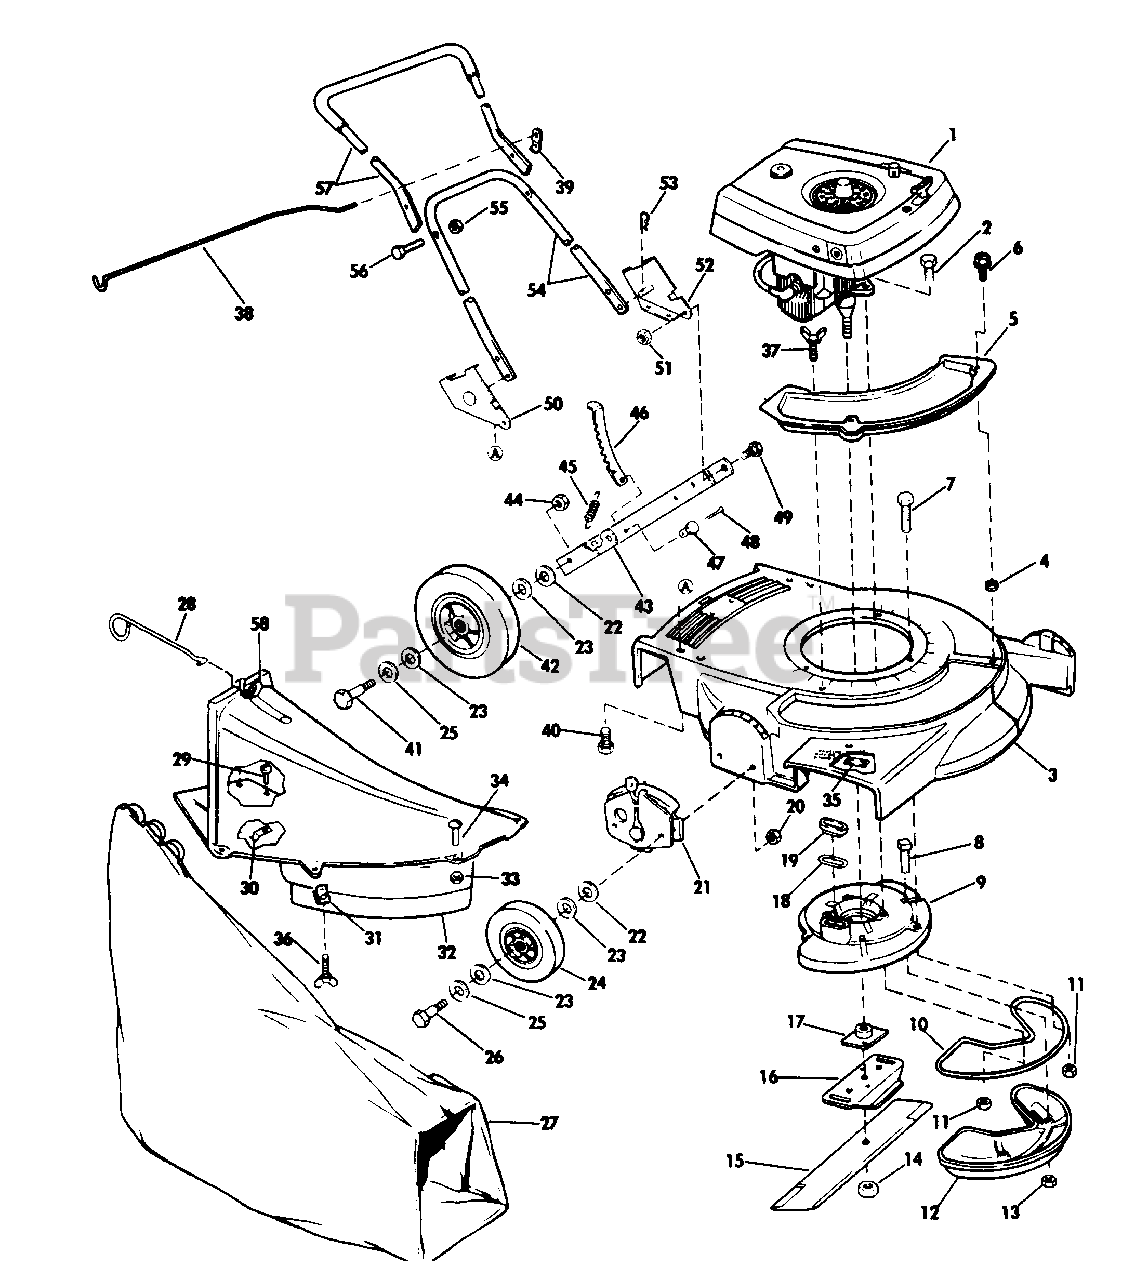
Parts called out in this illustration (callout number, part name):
1	Engine-Model D-408
2	Screw-Crankcase to Muffler Plate
3	Housing Assembly 19"
4	Grommet
5	Cover-Chute Opening (Plastic)
6	Hex Head Screw
7	Screw-Muffler Plate to Housing
8	Screw-Muffler to Muffler Plate
9	Muffler Plate
10	Gasket Muffler
11	Nut-Nylok
12	Muffler
13	Nut-Muffler
14	Nut-Blade
15	Blade 19"
16	Stiffener-Blade
17	Collar & Plate Assembly
18	Gasket-Exhaust
19	Sleeve-Exhaust Gasket
20	Nut-Wheel Lever Bolt
21	Height Adjust Assy.
22	Washer
23	Felt Washer
24	Wheel & Tire Assembly 6"
25	Washer, Wheel Bolt Head
26	Bolt-Shoulder, Wheel Front
27	Bag & Frame Assembly
28	Wheel Guard
29	Screw
30	Speed Nut
31	Speed Nut
32	Skirt Assembly-Chute
33	Nut
34	Screw
35	Speed Nut
36	Wing Screw-Long
37	Wing Screw
38	Rod & Clip Assembly
39	Clip-Rod
40	Screw-Handle Bracket
41	Bolt-Rear Wheel
42	Wheel & Tire Assembly 8"
43	Bracket
44	Nut
45	Spring
46	Lever-Height Adjustment (Rear)
47	Pin
48	Cotter Pin
49	Bolt
50	Bracket-Handle, Right
51	Nut-Wheel Lever Bolt
52	Bracket-Handle, Left
53	Hairpin
54	Handle, Bottom
55	Nut-Handle
56	Screw-Handle
57	Handle & Grip Assembly-Top
58	Clip Assy.-Chute (Plastic)
58	Clip Assy.-Chute (Metal)
